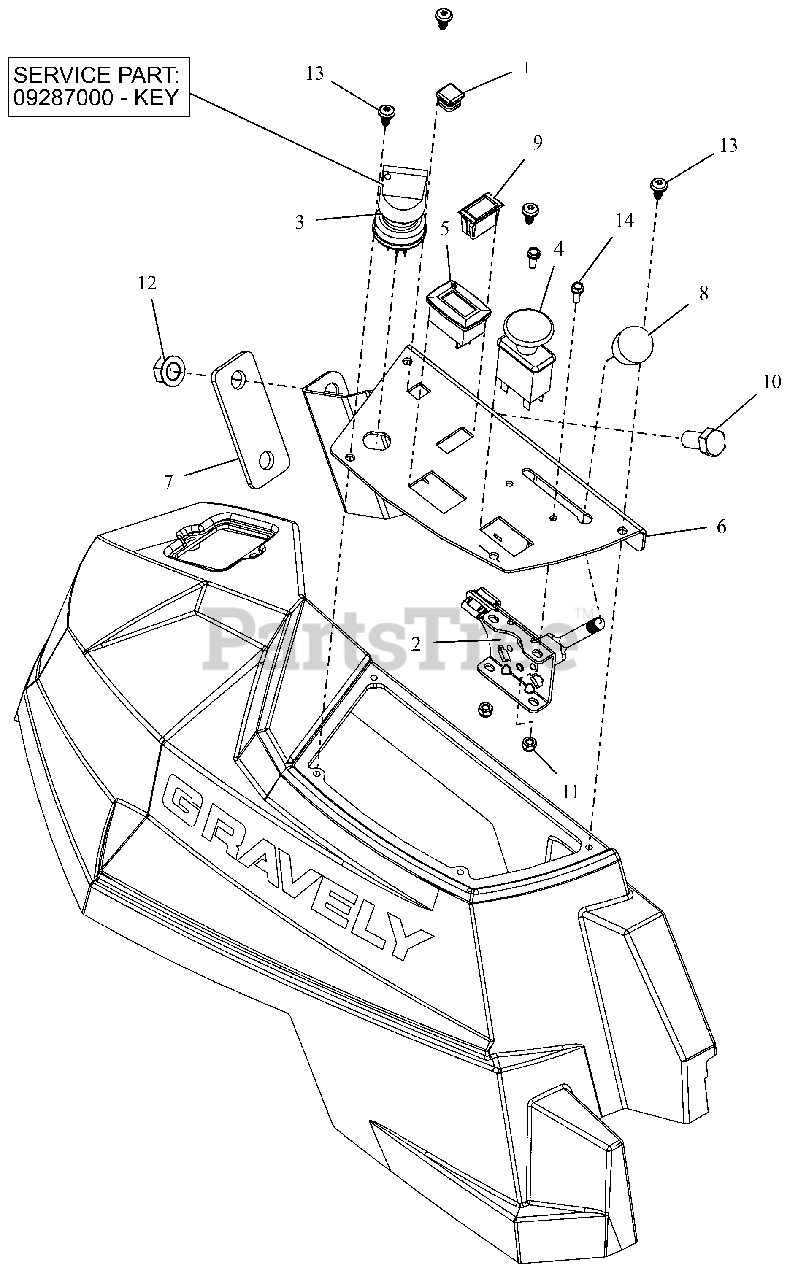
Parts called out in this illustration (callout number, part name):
1	PLUG, 5/8" SQ BLACK (14-20GA)
2	CABLE, PRO THROTTLE CONTROL
3	SWITCH, IGNITION
3	KEY, W/ SHIELD
4	SWITCH, CLUTCH
5	METER, HOUR W/MAINTENANCE
6	PANEL, HD CONTROL
7	PLATE, CONTROL PANEL SPACER
8	KNOB-CONTROL-BLACK .38-16X.50
9	SWITCH,BLANK
10	@BLT-HEX .50-13X1.00 GR5 YWZC
11	@NUT-LK-NYL 10-24 W/INSRT YWZC
12	@NUT-LK-TOP-FLG .50-13 YWZC
13	SCR-PAN .25-15X.50 6L H/LZB500
14	@SCR-MCH 10-24X.50 HWH YWZC
